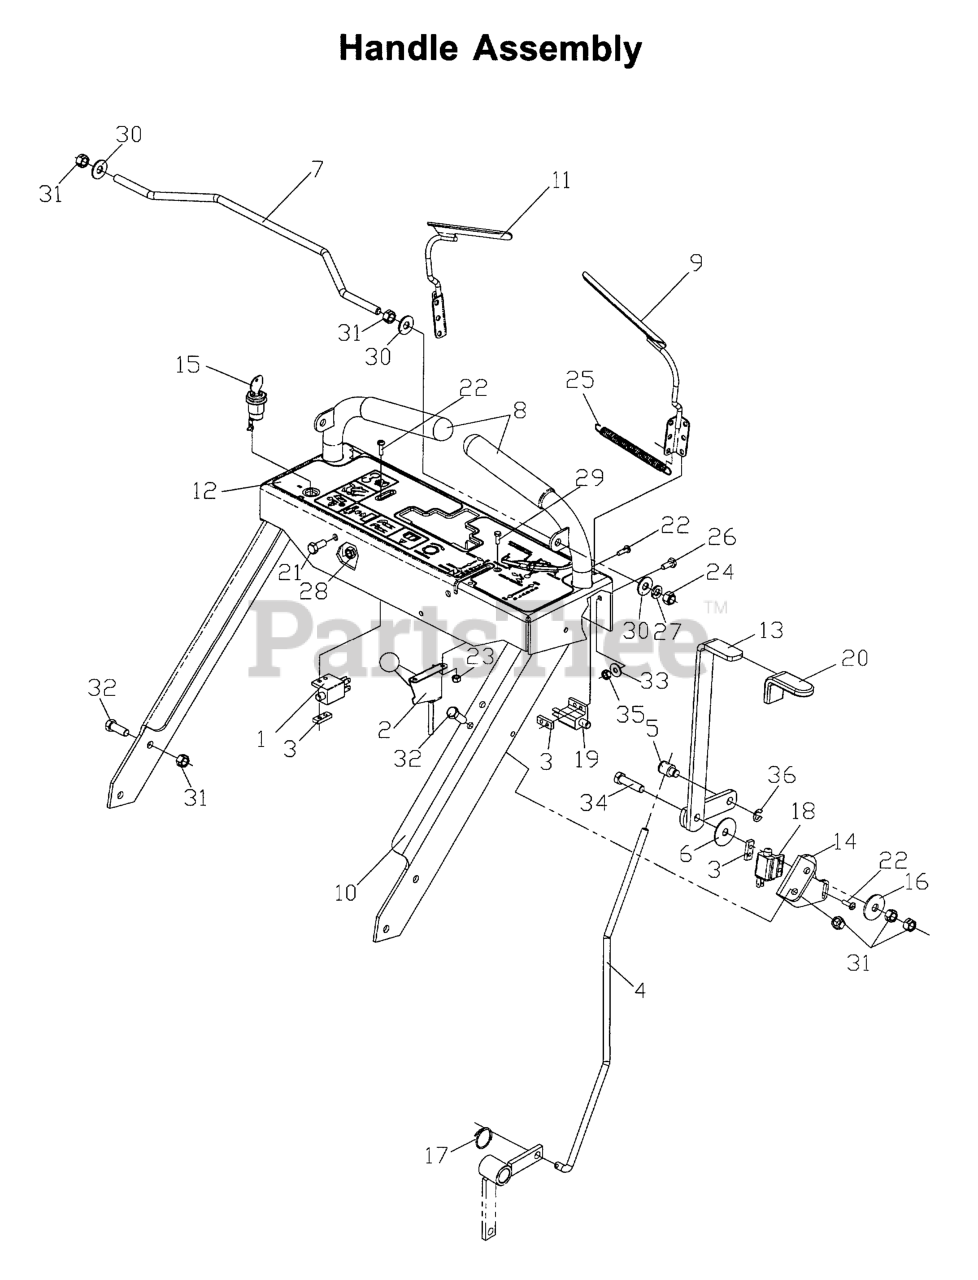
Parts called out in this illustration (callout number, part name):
1	SWITCH, INTERLOCK
2	THROTTLE CONTROL W/BALL KNOB
3	TAPPED PLATE
4	BLADE LINK
6	WASHER, FRICTION
7	NEUTRAL BAIL
9	OPER LEVER-LH
10	HANDLE W/DECAL
11	OPER LEVER - RH
12	CONSOLE DECAL
13	ENGAGEMENT LEVER
14	BLADE ENGAGEMENT BRK
15	KEY SWITCH, COMPLETE
16	CONE WASHER
21	HCS 5/16C X 3/4
22	SCREW #10-24 X 5/8
23	NUT 10-24 NYLOC
24	NUT 3/8-16 NYLOC
26	HCS 1/4C X 5/8
27	SLW 3/8 STD
28	NUT 5/16C CENTERLOCK
29	HCS #10-24 X 1/2
30	WASHER 3/8 FLAT
31	NUT 3/8C CENTERBLOCK
32	HCS 3/8-16X1.GRD.5.ZD
33	WASHER 1/4 FLAT
34	HCS 3/8C X 1 1/2
35	NUT 1/4C CENTER LOCK
36	E RING 3/8"
37	DECAL, ETS
